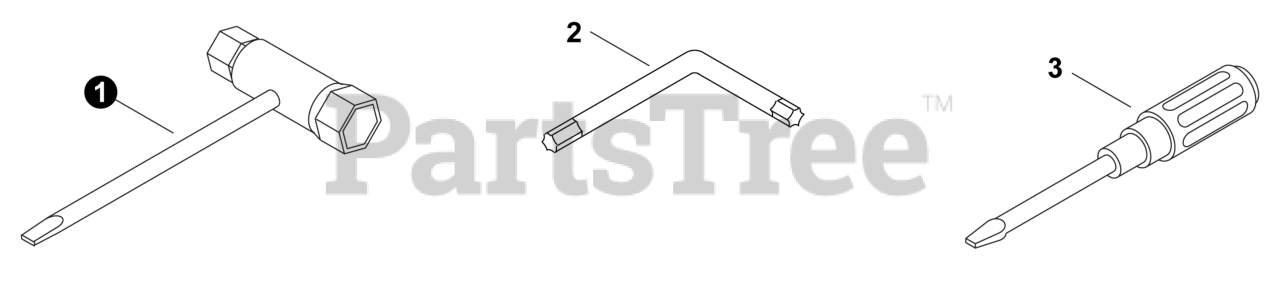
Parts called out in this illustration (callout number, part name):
1	T-WRENCH 13x19 L= 180
2	WRENCH, T27
3	SCREWDRIVER
